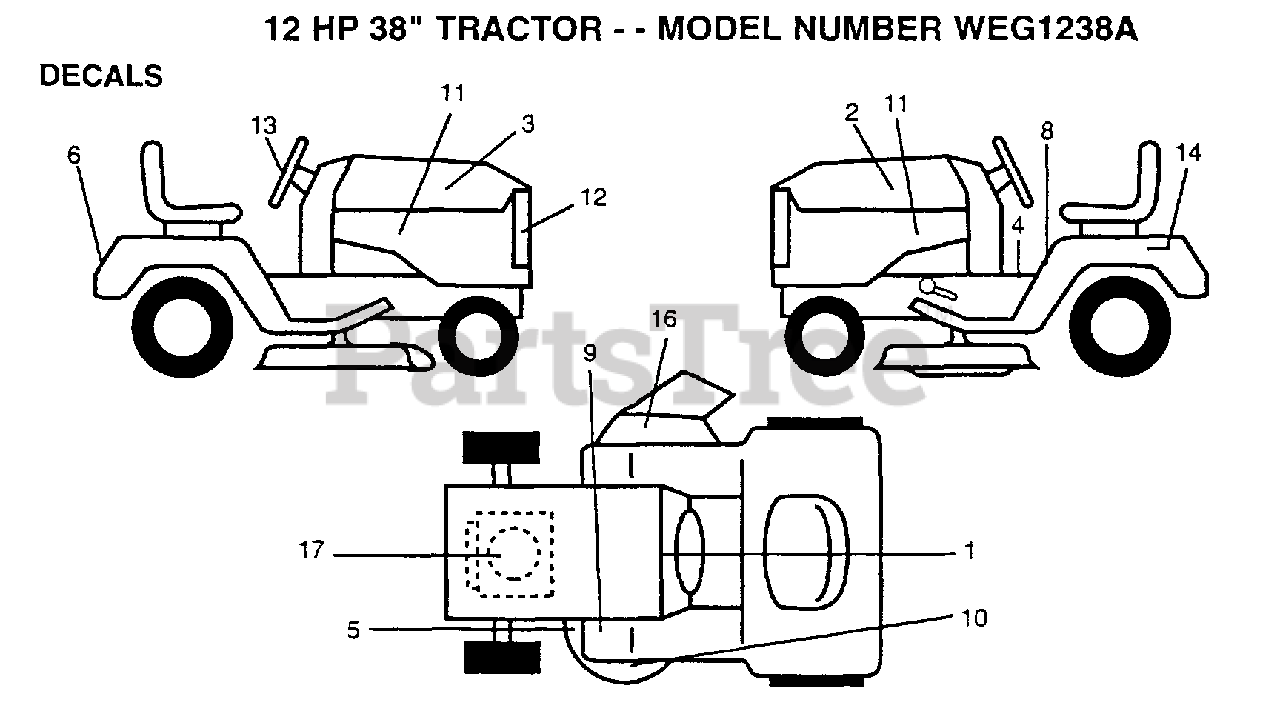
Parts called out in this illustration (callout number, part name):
1	DECAL.DASH.INSTR.
2	DECAL.HD.STRIP.LH
3	DECAL.HD.STRIP.RH
4	DECAL BRAK PARK
5	DECAL
6	DECAL.FENDER
8	DECAL CAUTION
9	DECAL T
10	DECAL.MOWER
11	DECAL.PNL.SIDE.12
12	DECAL.GRILL
13	DECAL.WHL.STRG.
14	DECAL
16	"DECAL, WARNING"
17	DECAL.ENG.271967
